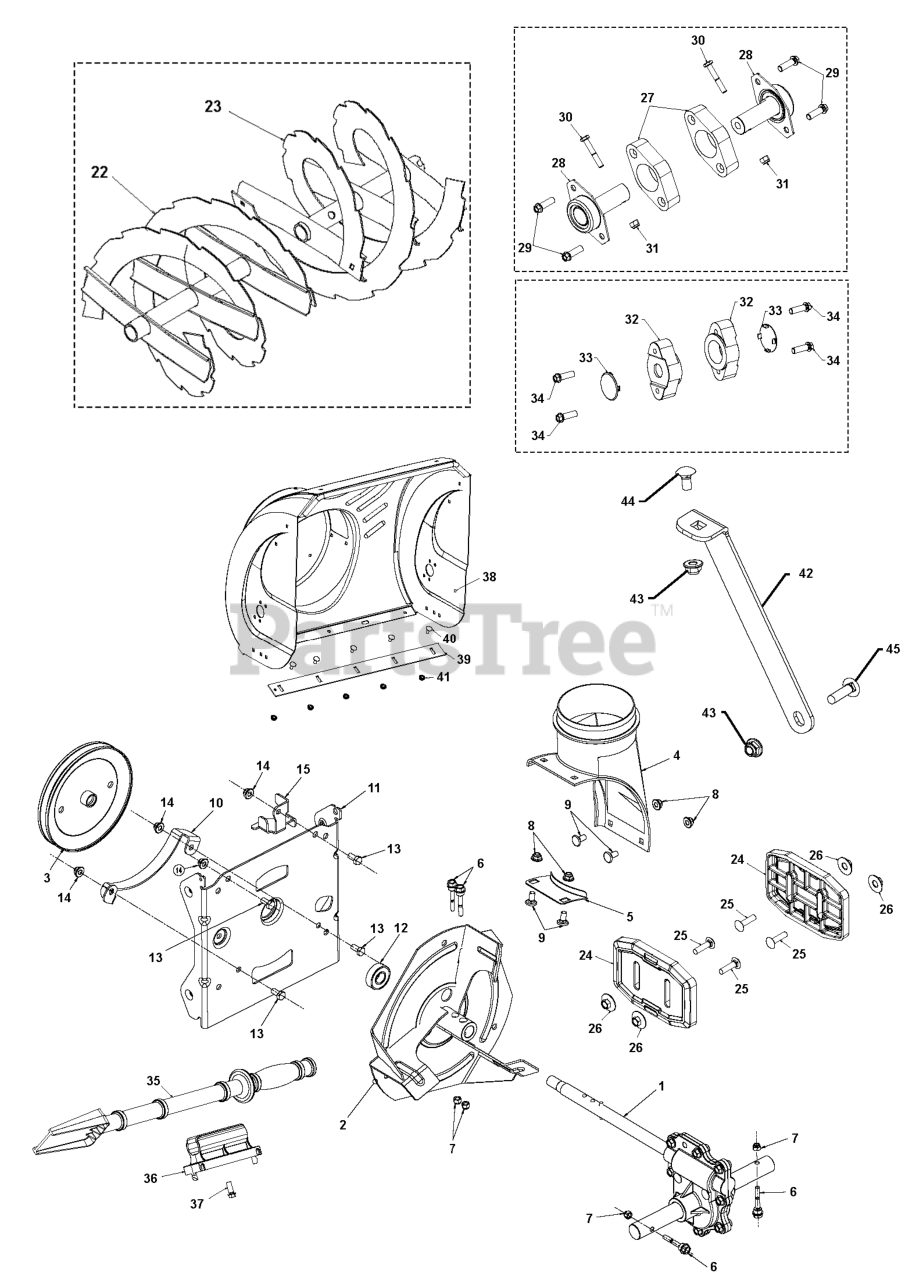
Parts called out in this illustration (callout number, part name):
1	TRANSMISSION.GEARBOX.ALUM.DD
1	Gears
1	KIT.GEARBOX.ALUM.DD.SHAFT
2	IMPELLER.STEEL.SNOW.BLACK
3	PULLEY SCREW ON 7.3
3	PULLEY SCREW ON 7.3 5/8
4	CHUTE.DISCHARGE.BASE
6	BOLT SHEAR HX HD 1/4-20 CLEAR
7	NUT HEXAGON 1/4-20 ST ZPB
7	LOCKNUT.NYLOC.1/4-20
8	NUT HEX FLG NYLOCK BLK 5_16-1
9	BOLT CARR WAFER BLK 5_16-18 X
10	BRACKET.BELT.KEEPER.LOWER.BLAC
11	BRACKET.AUG.HOUSING.INTER.BLAC
13	BOLT, HEX HEAD 5/16-18
14	NUTNYLOK.FLRANGE.5/16-18
15	GUIDE.LOWER.AUGER.BELT.479
22	AUGER.WELD.RIB.BUT.27.LH.GREY
23	AUGER.WELD.RIB.BUT.27.RH.GREY
24	PLATE.SKID.SHOE.COMPOSITE
25	BOLT CAR BLK 5/16-18 X 1-1/4
26	NUT.HEX.FL 5/16-18 TOP LCK BLK
26	NUT.CENTERLOCK.5/16-
27	BEARING RETAINER, PLASTIC
28	BALL BEARING AUGER BALL BEARIN
29	SCREW.HI-LO. 5/16 X 1.00
30	SCREW.HEX.HD1/4-20X
30	BOLT HEXAGON BOLT 1/4-20 X 1-5
31	LOCKNUT.NYLOC.1/4-20
31	NUT HEXAGON 1/4-20 ST ZPB
32	BEARING.AUGER.SHAFT
33	PLUG.BEARING.HOLE.HSG
34	SCREW.HI-LO. 5/16 X 1.00
35	CLEAN OUT TOOL
36	CLIP.CLEANOUT.TOOL
37	SCREW.HWH.13-16-5.8.BZP
38	KIT.AUGER.HOUSING.586184005
39	BAR.SCRAPER.27.PNT.BLACK
40	BOLT ROUND HEAD SQUARE NECK BO
41	NUT.FLANGE.5/16
42	BRACE SUPPORT GEARBOX 200 SERI
43	NUT HEX FLG NYLOCK BLK 5_16-1
44	BOLT CAR BLK 5/16-18 X 5/8
45	BOLT.CARRIAGE.5/16-18
